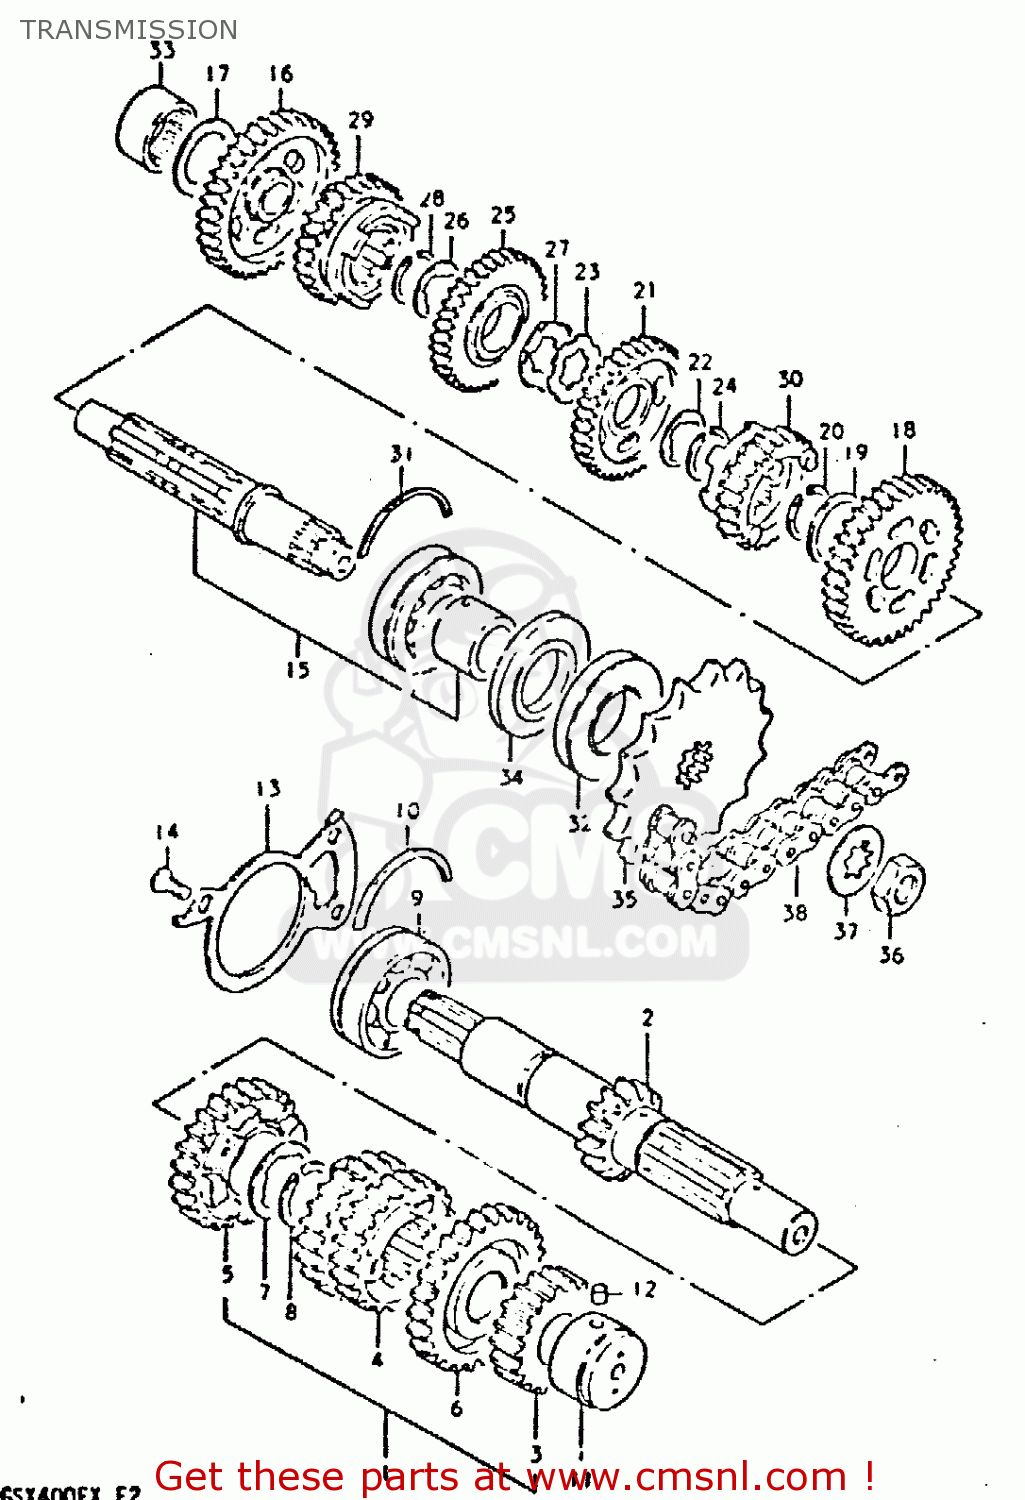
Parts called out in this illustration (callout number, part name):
1	SHAFT,COUNTER
2	SHAFT,COUNTER
3	GEAR,2ND DRIVE(NT:18)
4	GEAR,THIRD DRIVE
5	GEAR,FIFTH DRIVE
6	GEAR,SIXTH DRIVE
7	WASHER
8	CIRCLIP
9	BEARING(25X62X17)
10	C-RING
11	ROLLER BEARING (20X34X2
12	PIN
13	PLATE,COUNTERSHAFT BEARING
14	SCREW
15	SHAFT,DRIVE
16	GEAR,FIRST DRIVEN
17	WASHER
18	GEAR,SECOND DRIVEN
19	WASHER
20	CIRCLIP
21	GEAR,THIRD DRIVEN
22	WASHER,LOCK
23	WASHER,LOCK
24	CIRCLIP
25	GEAR,FOURTH DRIVEN
26	WASHER,LOCK
27	WASHER
28	CIRCLIP
29	GEAR,5TH DRIVEN(NT:25)
30	GEAR,SIXTH DRIVEN
31	C-RING
32	SEAL,OIL(32X64X8)
33	ROLLER BEARING (20X34X1
34	SEAL,OIL(32X62X5.5)
35	SPROCKET,ENGINE
36	NUT
37	WASHER
38	CHAIN ASSEMBLY,DRIVE
